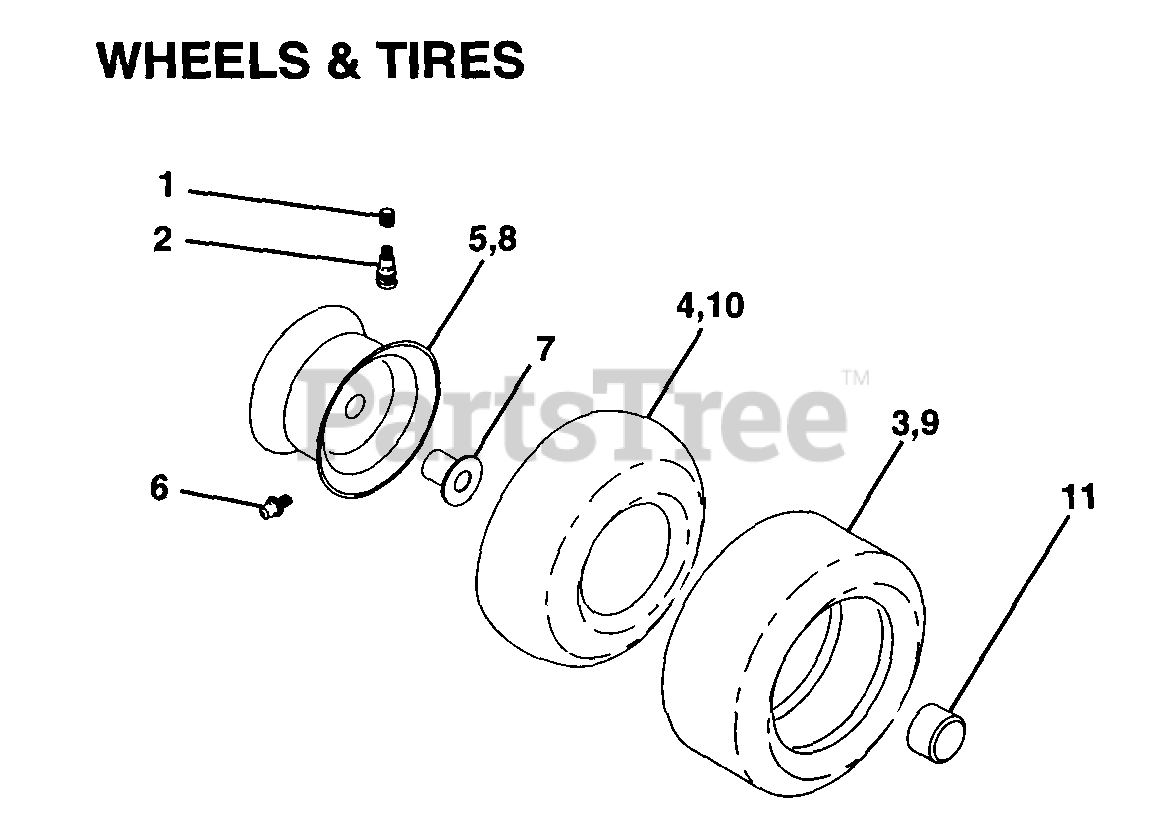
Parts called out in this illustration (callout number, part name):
1	Cap Valve Tire
2	Stem Valve
3	Tire F Ts 15 x 6 0 - 6 Service
4	Tube Front (Service Item Only)
5	Rim Asm 6" front Silver Service
6	Fitting Grease (Front Wheel Only)
7	Bearing Flange (Front Wheel Only)
8	Rim Asm 8" rear Silver Service
9	Tire R Ts 18 x 8 5-8 C Service
10	Tube Rear (Service Item Only)
11	Cap Axle Blk 1 50 x 1 00
